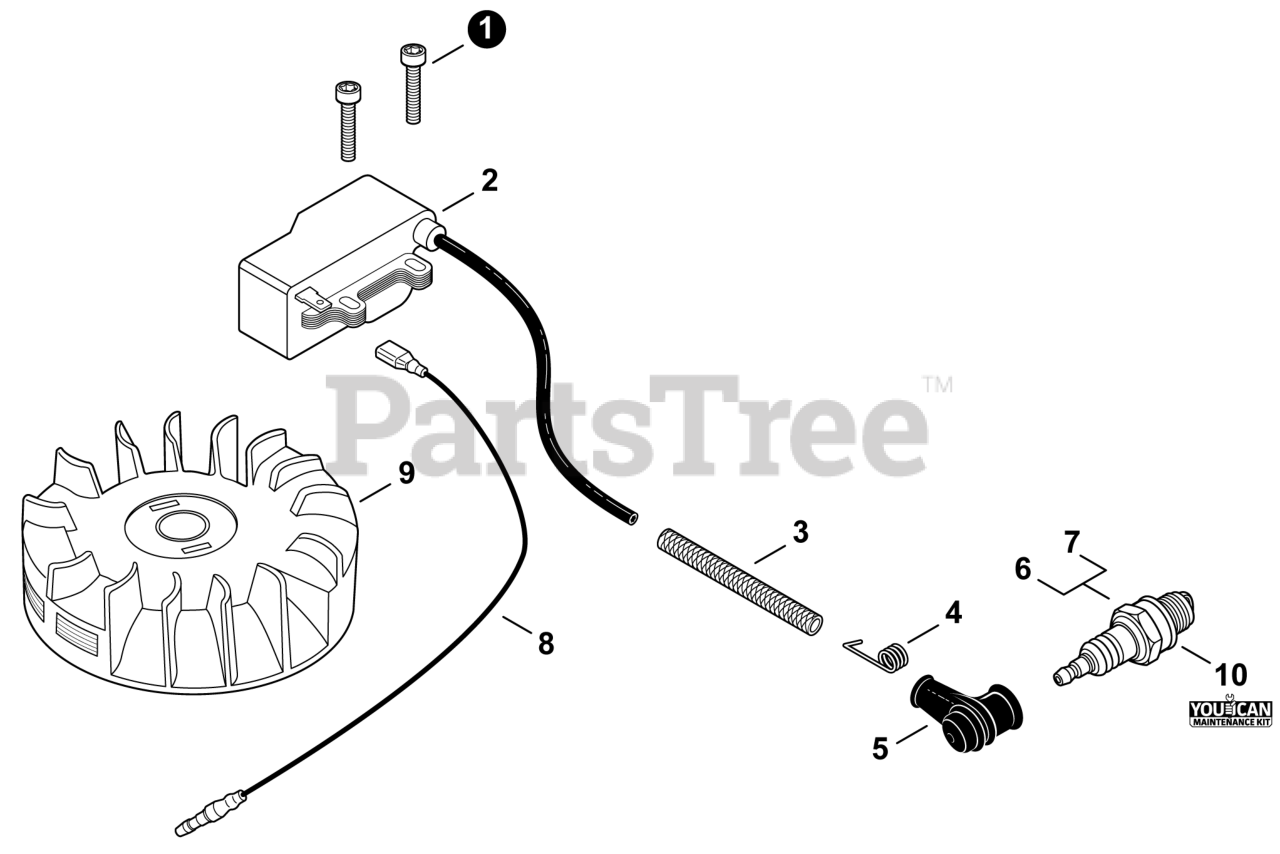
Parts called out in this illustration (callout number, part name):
1	BOLT, TORX 4×20
2	COIL, IGNITION
3	TUBE, INSULATOR
4	TERMINAL, SPARK PLUG
5	CAP, SPARK PLUG
6	SPARK PLUG - BPM8Y
7	SPARK PLUG - BPMR8Y
8	LEAD - IGNITION
9	FLYWHEEL
10	TUNE-UP KIT - YOUCANT
